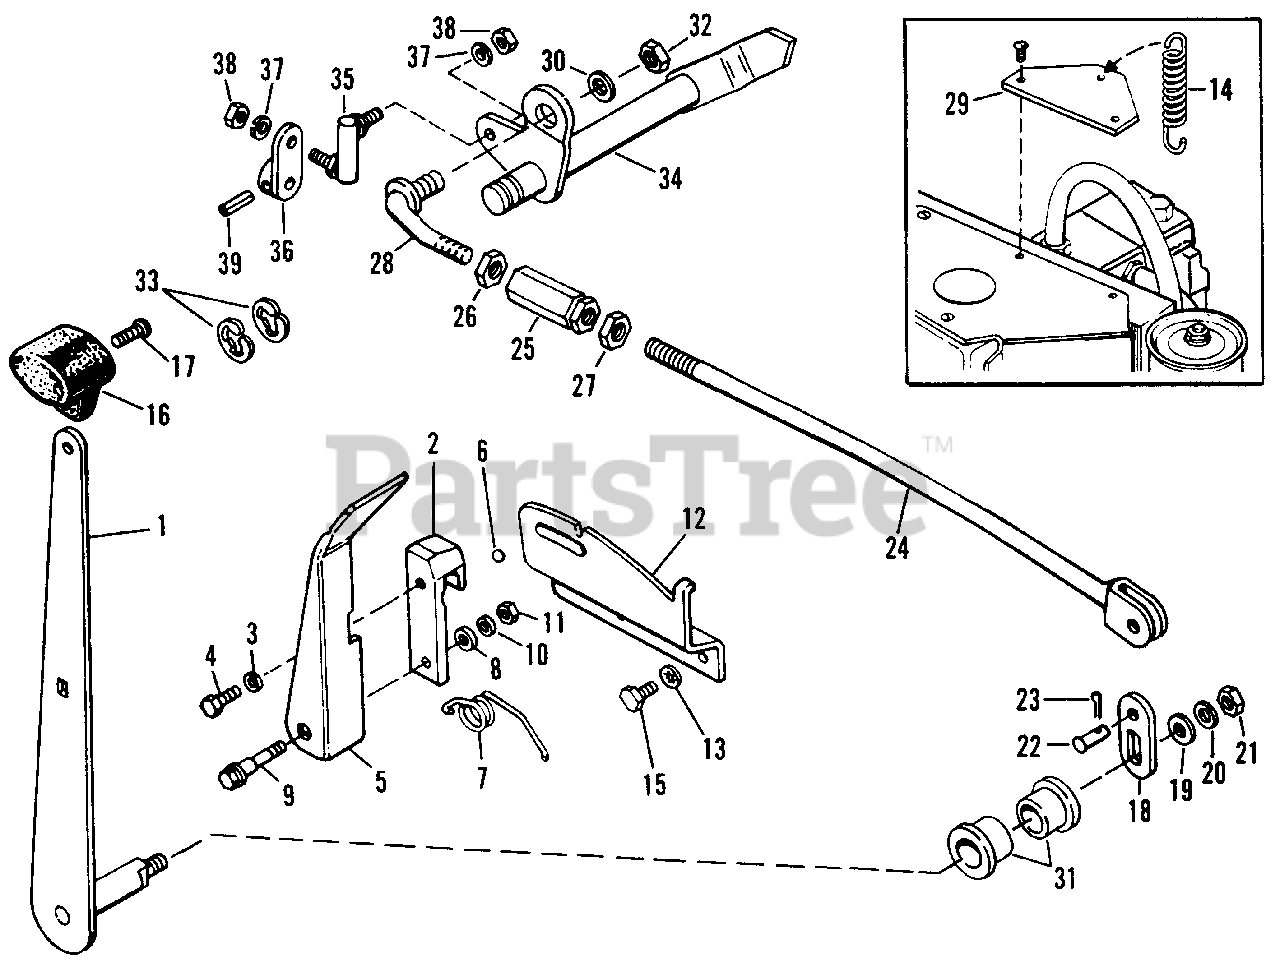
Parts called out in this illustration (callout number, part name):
1	Lever Assembly
2	Stop Clamp
3	Lockwasher, 1/4" Std.
4	Hex Capscrew, 1/4"-20 N.C. x 1/2"
6	Shift Ball Handle, 5/16"
9	Shoulder Bolt
10	Plain Washer, 1/4"
11	Full Hex Lock Nut, 1/4"-20
13	Shakeproof Lockwasher, 5/16"
15	Special Screw
17	Screw, Thd. Form, 1/4"-20 x 7/8"
19	Plain Washer, 3/8"
20	Lockwasher, 3/8"
21	Full Hex Nut, 3/8"-16
23	Cotter Pin, 3/32" x 3/4"
24	Rod Assembly Control, Front
25	Turn Buckle
26	Full Hex Nut, 7/16"-14 L.H.
27	Full Hex Nut, 7/16"-14 R.H.
28	Rod Assy., Rear Control
29	Spring Clip
30	Plain Washer, 5/16"
32	Lock Nut, 3/8"-16
33	"E" Ring
34	Shaft Assembly Control
35	Ball Joint, Double End
36	Link Assembly Control
37	Lockwasher, 5/16"
38	Full Hex Nut, 5/16"-24
39	Roll Pin, 1/4" x 1-1/4"
